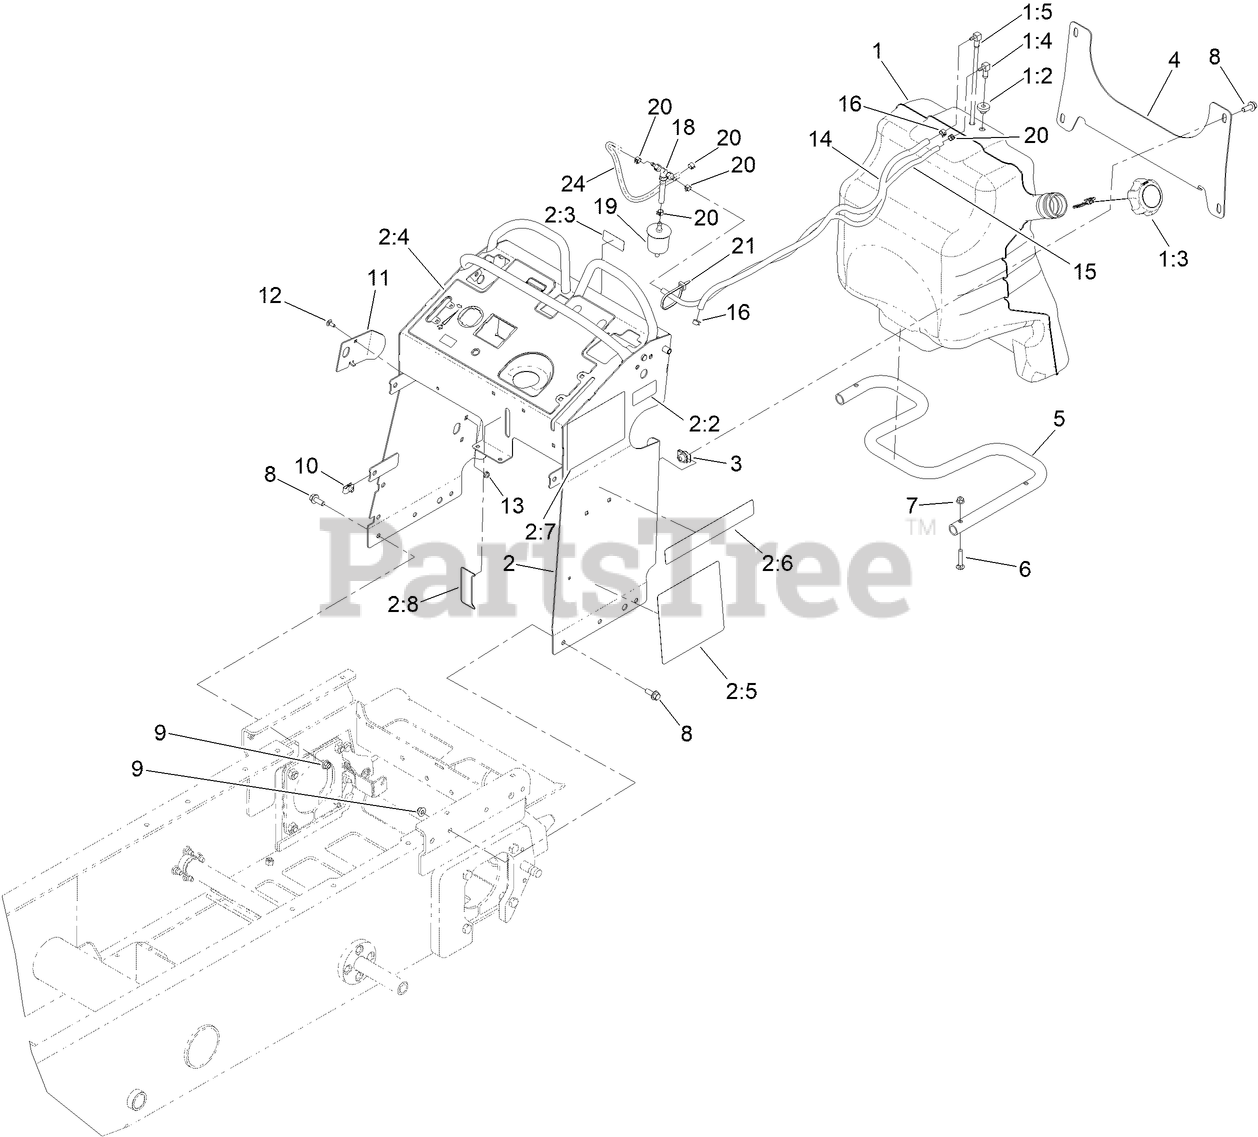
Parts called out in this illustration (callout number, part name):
1	FUEL TANK ASM
1:2	BUSHING
1:3	CAP-FUEL
1:4	FITTING-ELBOW, 90 DEG
1:5	FUEL TUBE ASM
2	TOWER ASM
2:2	DECAL-FILL, FUEL
2:3	DECAL-FUSE
2:4	DECAL-CONTROL PANEL
2:5	DECAL-SERVICE
2:6	DECAL, MBTX-2500
2:7	DECAL-SRVSW5X7
2:8	DECAL-LEVEL, OIL
3	NUT-TINNERMAN
4	BRACKET-CROSS
5	TUBE-FUEL TANK MOUNT
6	BOLT-CAR
7	NUT-HF, NI
8	SCREW-HHF
9	NUT-HF, NI
10	NUT-CLIP, U
11	PLATE-STRIKER
12	SCREW-CARR
13	NUT-HF
14	HOSE-FUEL
15	HOSE-FUEL
16	CLAMP-HOSE
18	TEE AND CHECK
19	FILTER-FUEL
20	CLAMP-HOSE
21	TIE-CABLE
24	HOSE-VENT
